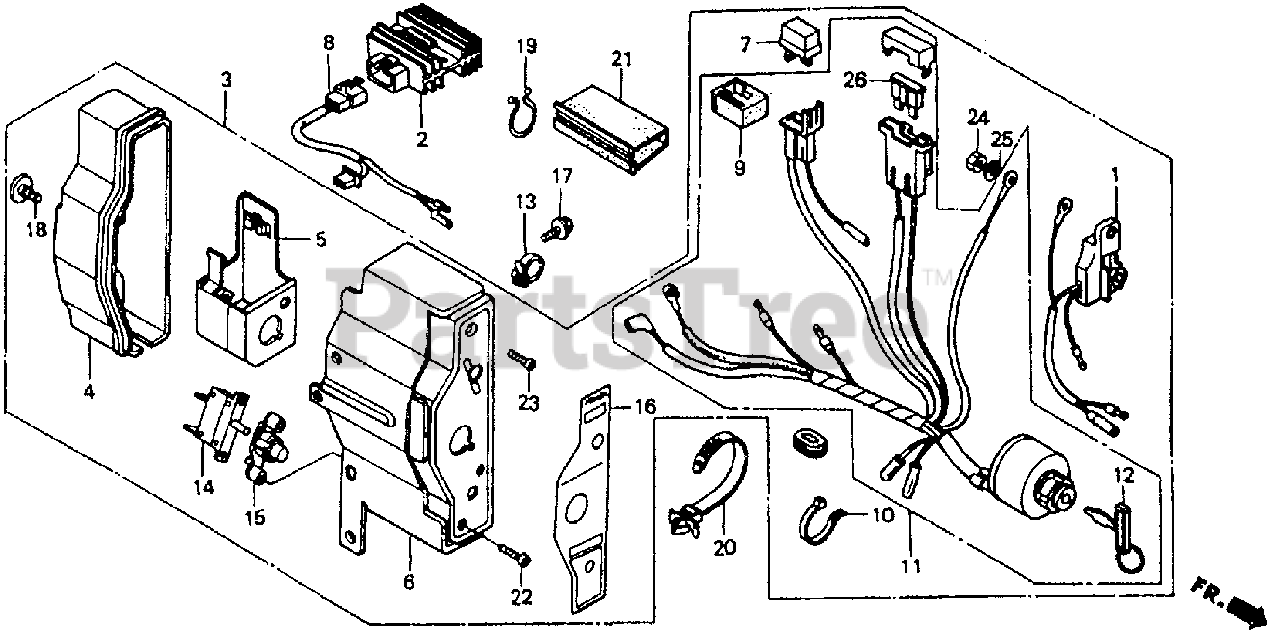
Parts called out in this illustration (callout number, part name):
1	ALERT UNIT, OIL (SEL)
2	RECTIFIER ASSY., REGULATOR
3	BOX ASSY., CONTROL (10A) *R8* (Honda Code 4328779). (EXTERNAL-ALERT) (BRIGHT RED)
4	CASE, CONTROL
5	BRACKET, CASE MOUNTING
6	PANEL, CONTROL *R8**R8* (Honda Code 4089215). (BRIGHT RED)
8	SUB-WIRE HARNESS ASSY.
10	BAND
11	SWITCH ASSY., COMBINATION
12	KEY
13	HOLDER, STOP SWITCH WIRE
16	MARK, CONTROL BOX (Honda Code 2537074). (EXTERNAL-ALERT-REG)
17	BOLT, FLANGE (6X12) (CT200)
18	SCREW, SPECIAL (6X12)
19	CLIP, PURSE LOCK
20	STRAP, CABLE (118MM) *NH1L* (Honda Code 1170653). (BLACK)
21	TUBE, FASTENER (30)
23	SCREW, PAN (4X12)
24	NUT, HEX. (4MM)
25	WASHER, SPRING (4MM)
26	FUSE, BLADE (15A)
